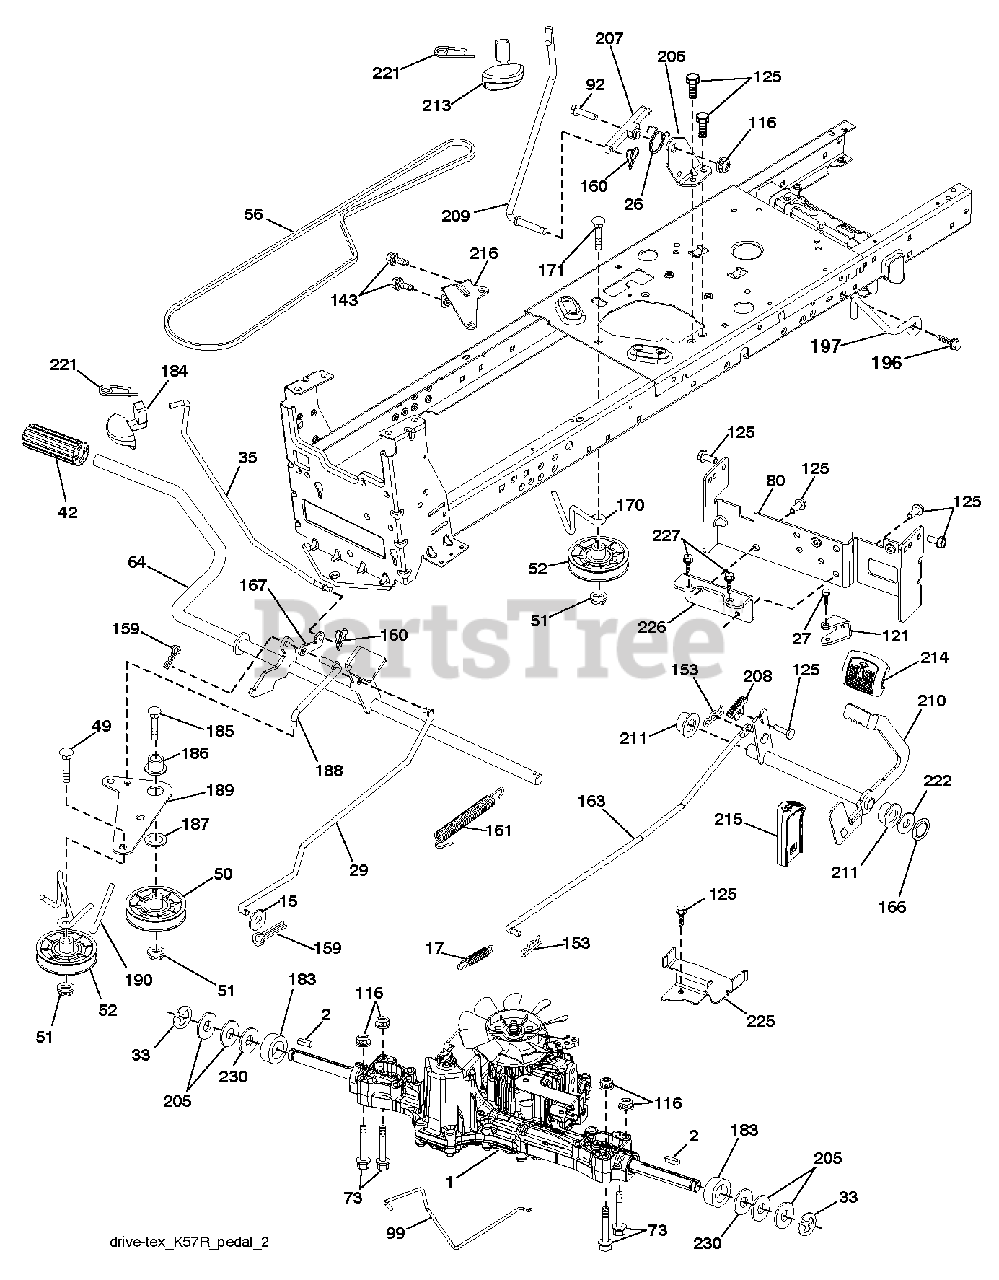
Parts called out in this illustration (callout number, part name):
2	SQUARE KEY
15	WASHER
17	SPRING.BRAKE.K46.GREEN
26	SPRING.RETURN.CRUISE
27	SCREW
29	ROD.BRAKE.K46
35	ROD.BRAKE.PARTK.HUSQ.TEX
42	PEDAL COVER T
50	IDLER.FLAT.910.OFFSET
51	NUT LOCK FLG 3/8-16 UNC
52	IDLER.V-GROOVE.910.OFFSET
56	V-BELT.MOWER.92.40.42/K46
64	SHAFT.ASM.PEDAL.BRK.CNTR
73	BOLT
80	STRAP.TORQUE.K46.K57R.TT
92	BOLT
99	ROD.SPRING.BYPASS.K46.LT.Z
116	NUT LOCK HEX FLANGE 5/16-18
121	BRACKET.TORQUE.K57R.3POINT
125	SCREW
143	SCREW LT
153	RETAINER M
159	COTTER PIN
160	RETAINER CLIP
161	SPRING, RETURN LT
163	ROD.CONTROL.PEDAL.K46
166	NUT.PUSH.625
167	LATCH.BRAKE.SPRING
170	KEEPER.V-IDLER.CENTER.
171	BOLT
183	SPACER AXLE
184	RB HANDLE.PARKG.BRK.HUS/PRED
186	SPACER.RETAINER
187	WASHER 12/32X2X10GA
188	RP LINK.CLUTCH.GROUND.DRIVE
189	BELLCRANK.GROUND.DRIVE.TEX.
190	KEEPER.BELLCRANK.DRIVE
196	SCREW 3/8-16X1
197	LINK.CLUTCH.ANIT-ROTAT
206	BRKT.MOUNT.LATCH.CRUIS
207	LATCH.CONTROL.CRUISE
208	GEAR.SECTOR.CONTROL.CR
209	ROD.CONTROL.CRUISE.GT.
210	ROCKER.ASM.PEDAL.CONTR
211	BEARING.NYLON
213	KNOB.CONTROL.CRUSIE.HU
214	PEDAL.FORWARD.PAD.TEX
215	PEDAL.REVERSE.TEX.GT.4
216	BRACKET.PULLEY.IDLER.W/TEX
221	RETAINER.SPRING.CLIP.H
222	WASHER 21/32 X 1-1/4 X 10 GA.
225	KEEPER.BELT.TRANSAXLE.K46
226	BRACKET.MOUNT.TORQUE.K46.TLT
227	SCREW
230	WASHER.HARDENED
